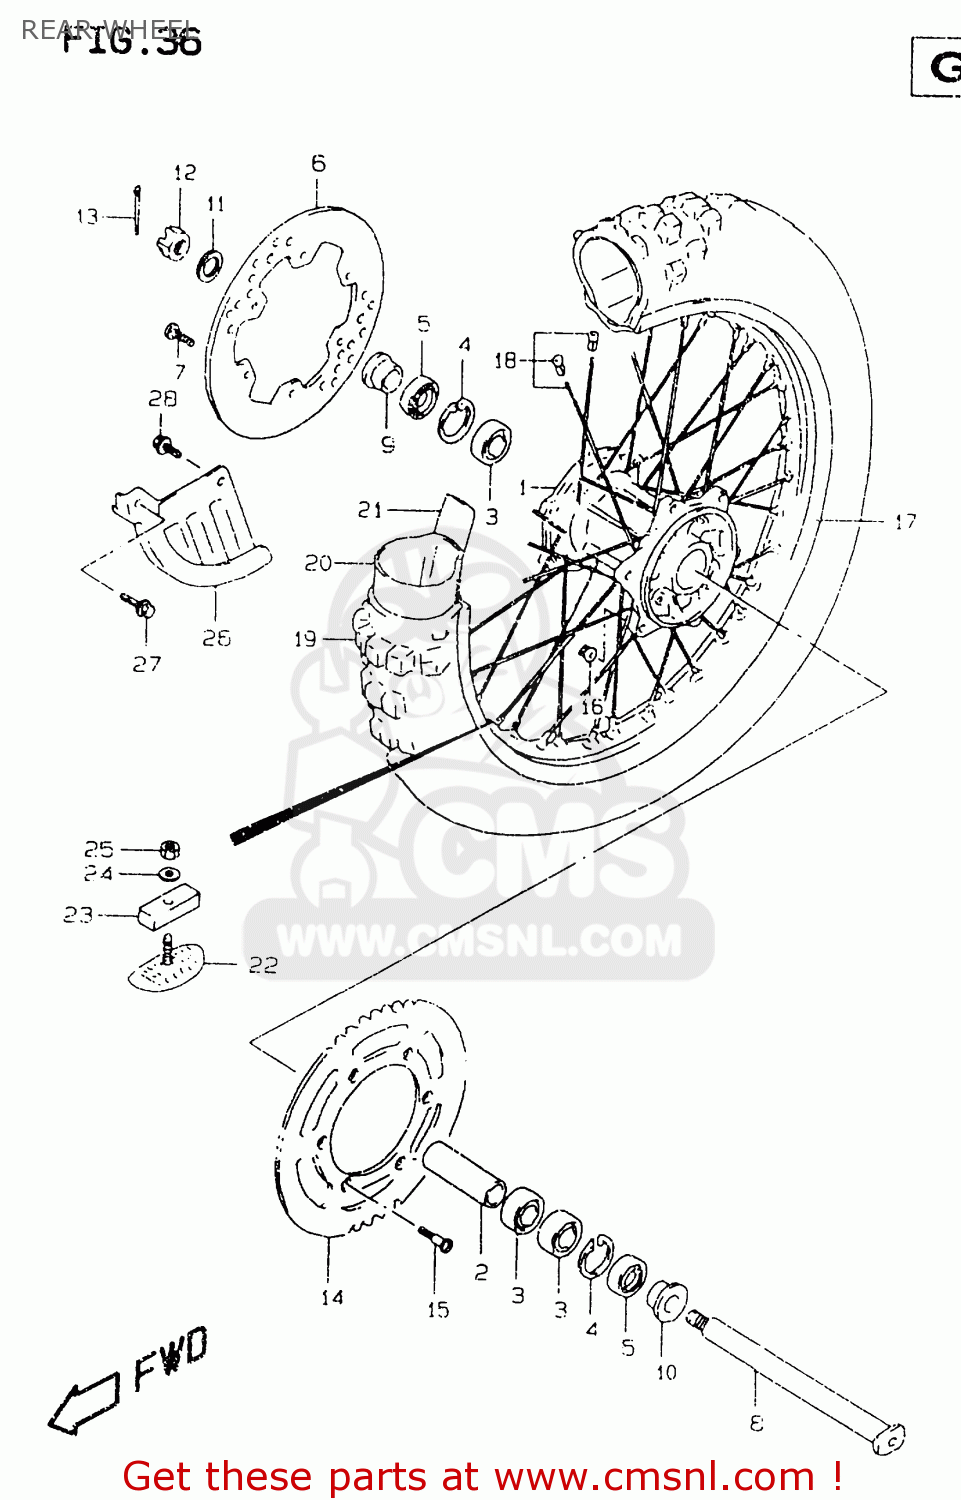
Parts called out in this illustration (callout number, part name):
1	HUB,RR WHEEL
2	SPACER,RR HUB BEARING
3	BEARING
4	CIRCLIP
5	SEAL(29X42X6)
6	DISC,RR BRAKE
7	SCREW
8	AXLE,RR
9	SPACER,RR AXLE
10	SPACER,RR AXLE
11	WASHER(19X32X3.2)
12	NUT
13	PIN,COTTER
14	SPROCKET,RR(NT:49)
15	BOLT(8X30.5)
16	NUT
17	RIM,REAR WHEEL (1.85X19)(A
18	SPOKE SET,RR WHEEL
19	TIRE,REAR 100/90-19
20	TUBE
21	PROTECTOR,WHL INR TUBE
22	STOPPER,BEAD(1.85)
23	CUSHION,BEAD STOPPER
24	WASHER
25	NUT
26	COVER SET,RR BRAKE DISC
27	BOLT
28	BOLT
